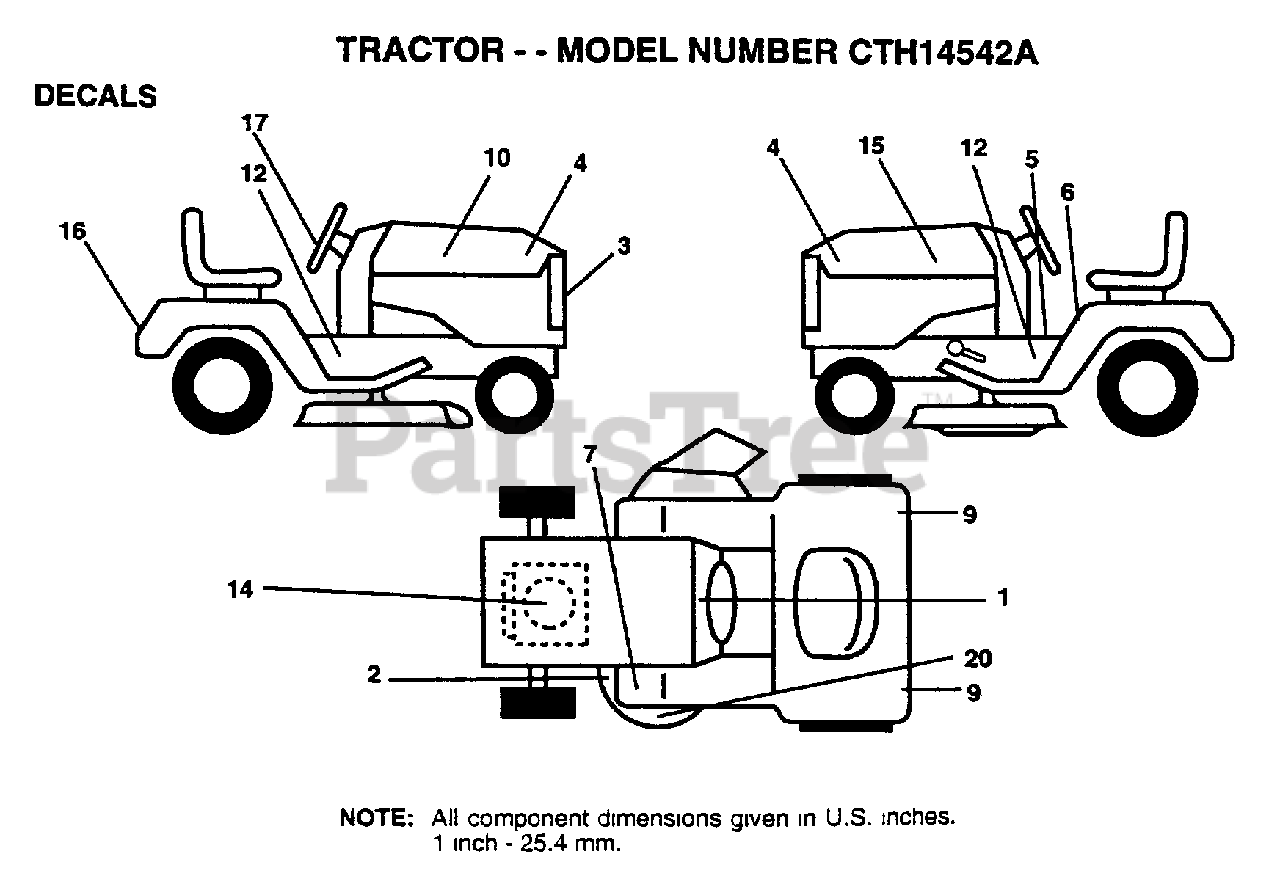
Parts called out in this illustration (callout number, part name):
1	DECAL.DASH.INST.
2	DECAL
3	DECAL.GRILLE
4	DECAL.INS.HD.RALL
5	DECAL BRAK PARK
6	DECAL
9	REFLECTOR-TAIL YT
10	DECAL.HD.RH.RALLY
12	DECAL CHAS 42 HYD
14	DECAL, ENGINE
15	DECAL.HD.LH.RALLY
16	DECAL.FENDER
17	DECAL INST STRWHL
